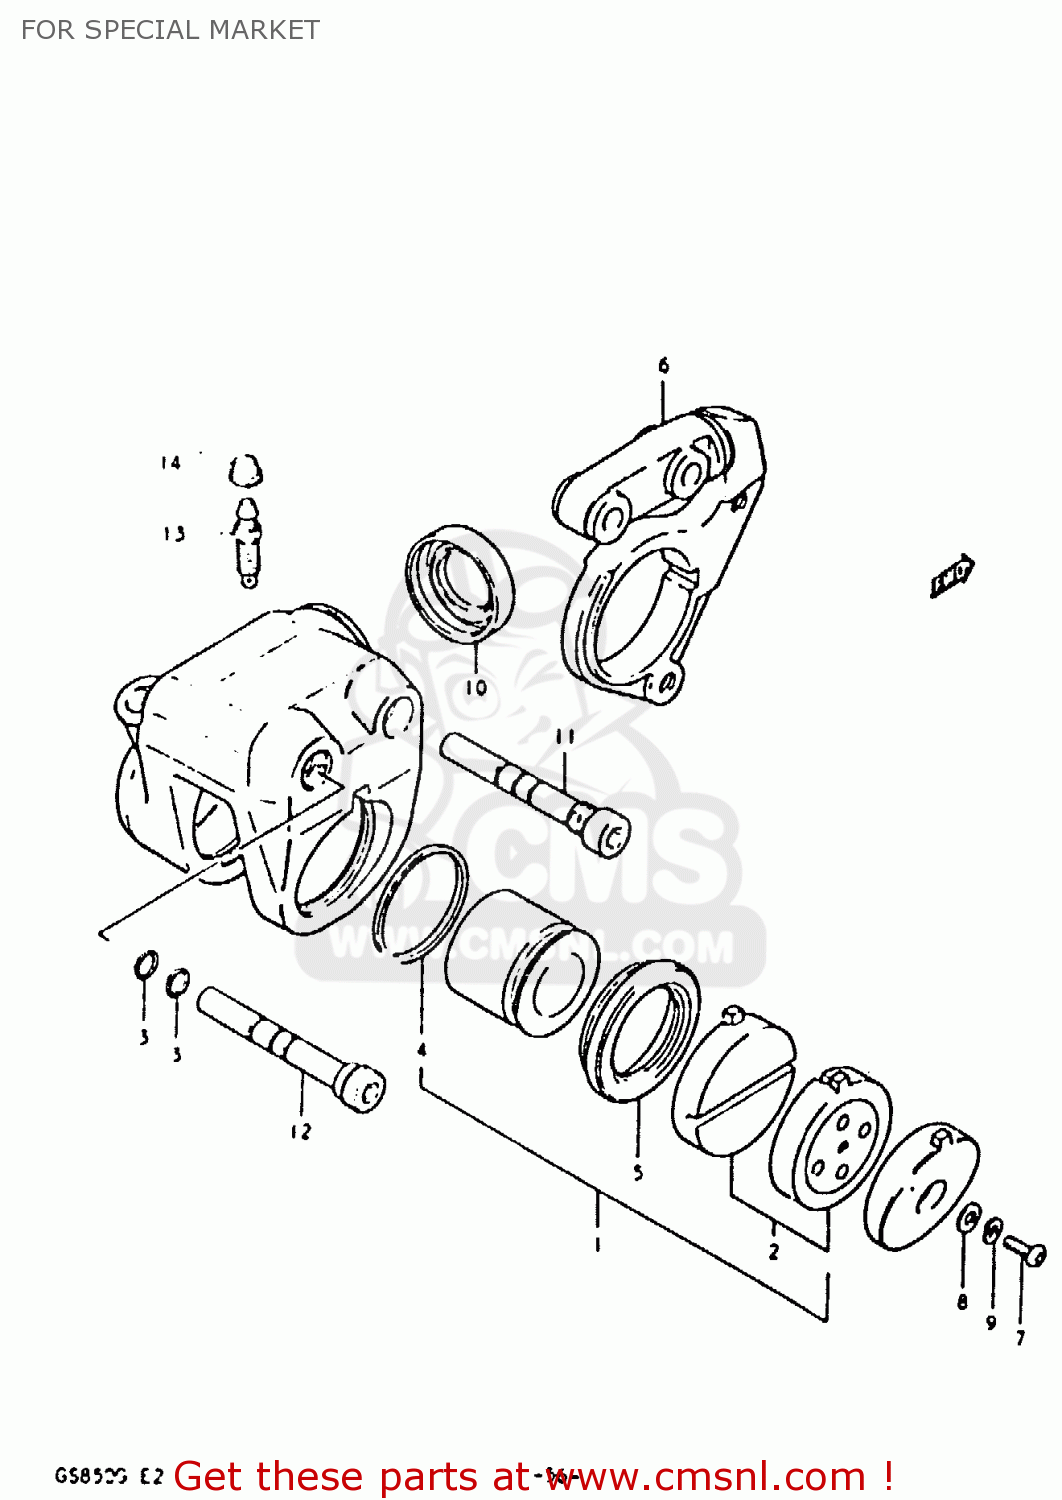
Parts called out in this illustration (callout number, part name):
1	PISTON & PAD SET
2	PAD SET (MCA)
3	O RING,AXLE CALIPER
4	SEAL,PISTON
5	BOOT,PISTON
6	HOLDER,CALIPER
7	SCREW
8	WASHER
9	LOCK WASHER
10	BOOT,HOLDER
11	AXLE,CALIPER
12	AXLE NO.2
13	BLEEDER
14	CAP,BLEEDER PL
